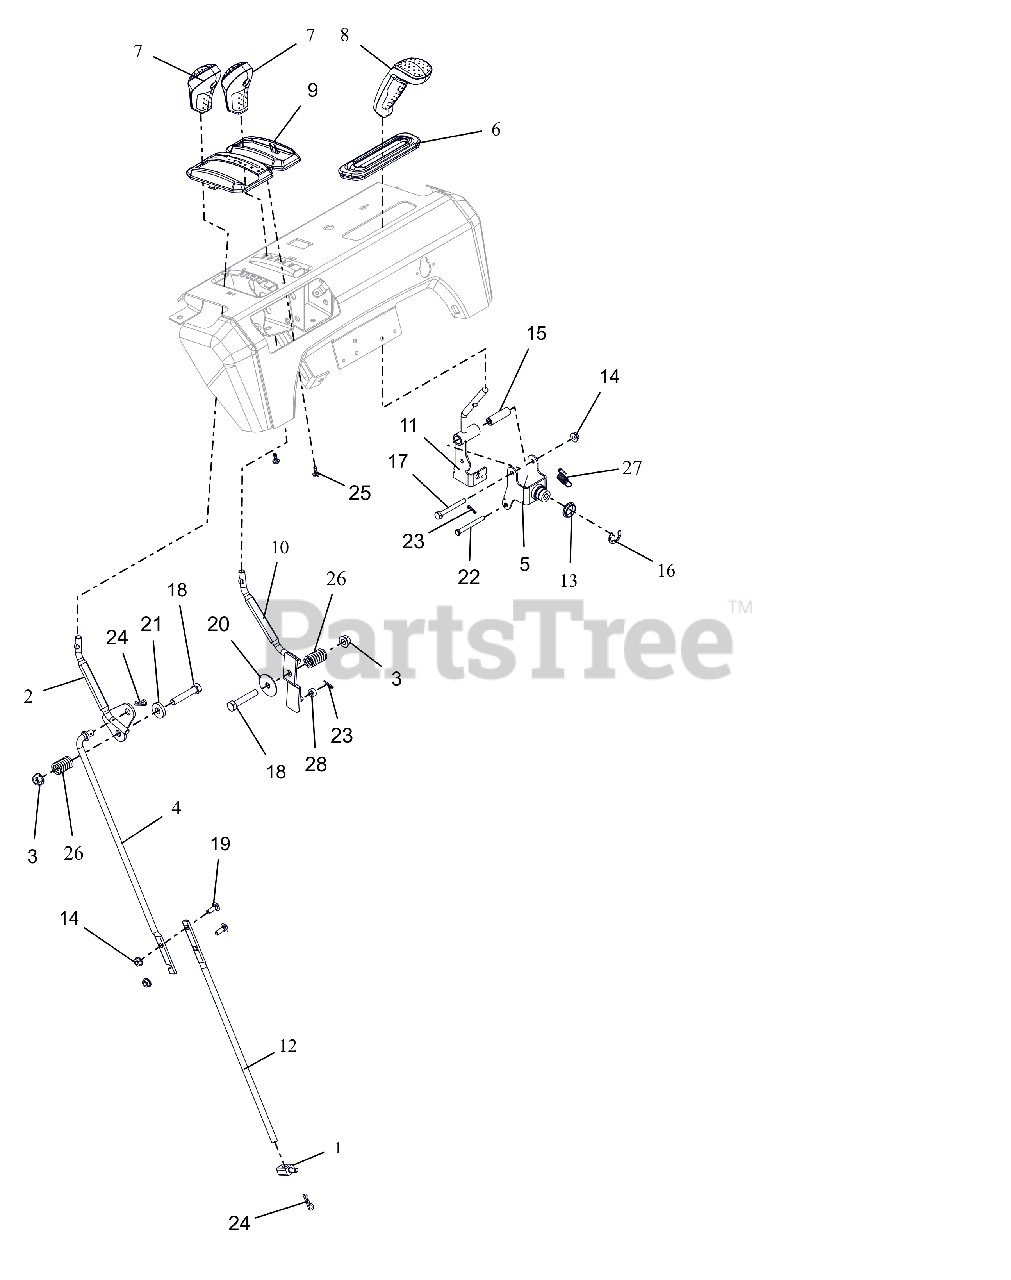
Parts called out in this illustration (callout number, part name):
1	PIVOT,SHIFT ROD .375-16(TRUNN)
2	WELDMENT,LG DASH SPEED CONTROL
3	NUT-LK-TOP-FLG .38-16 ZC120
4	ROD, SHIFT - UPPER
5	WELDMENT, CONTROL BRACKET
6	GROMMET, BOOT, QUICK TURN
7	KNOB, CONTROL, DASH
8	HANDLE, QUICK TURN, ASM
9	BEZEL, SHIFT - FRICTION SNOW
10	WELDMENT,LG DASH DEFL CONTROL
11	WELDMENT, CONTROL LEVER
12	ROD, SHIFT-LOWER (LG DASH DLX)
13	BUSHING, POLYLINER-.75 SNAPIN
14	NUT-LK-CTR-FLG .25-20 ZC120
15	BSHG, SLV .265X.505X1.665
16	E-RING .750X.050
17	BLT,HEX .25-20X2.25 G5 ZCC
18	BLT,HEX .38-16X2.00 G5 ZCC
19	BLT, RHSN .25-20X.750 G5 ZCC
20	WSHR,FLT .380X1.50X.062 ZCC
21	WSHR, FLT .406X1.00X.188 ZCC
22	PIN, CLEVIS - .25 X 2.25 ZCC
23	PIN, HAIR #178 .06X.77 ZCC
24	PIN, HAIR #213 .08X1.19 ZCC
25	SCR, PLASTIC #10X.50
26	SG-COMP .125X.781X1.250
27	SPRING-EXT .047X.438X1.45
28	BSHG-SLV .265X.500X.219
